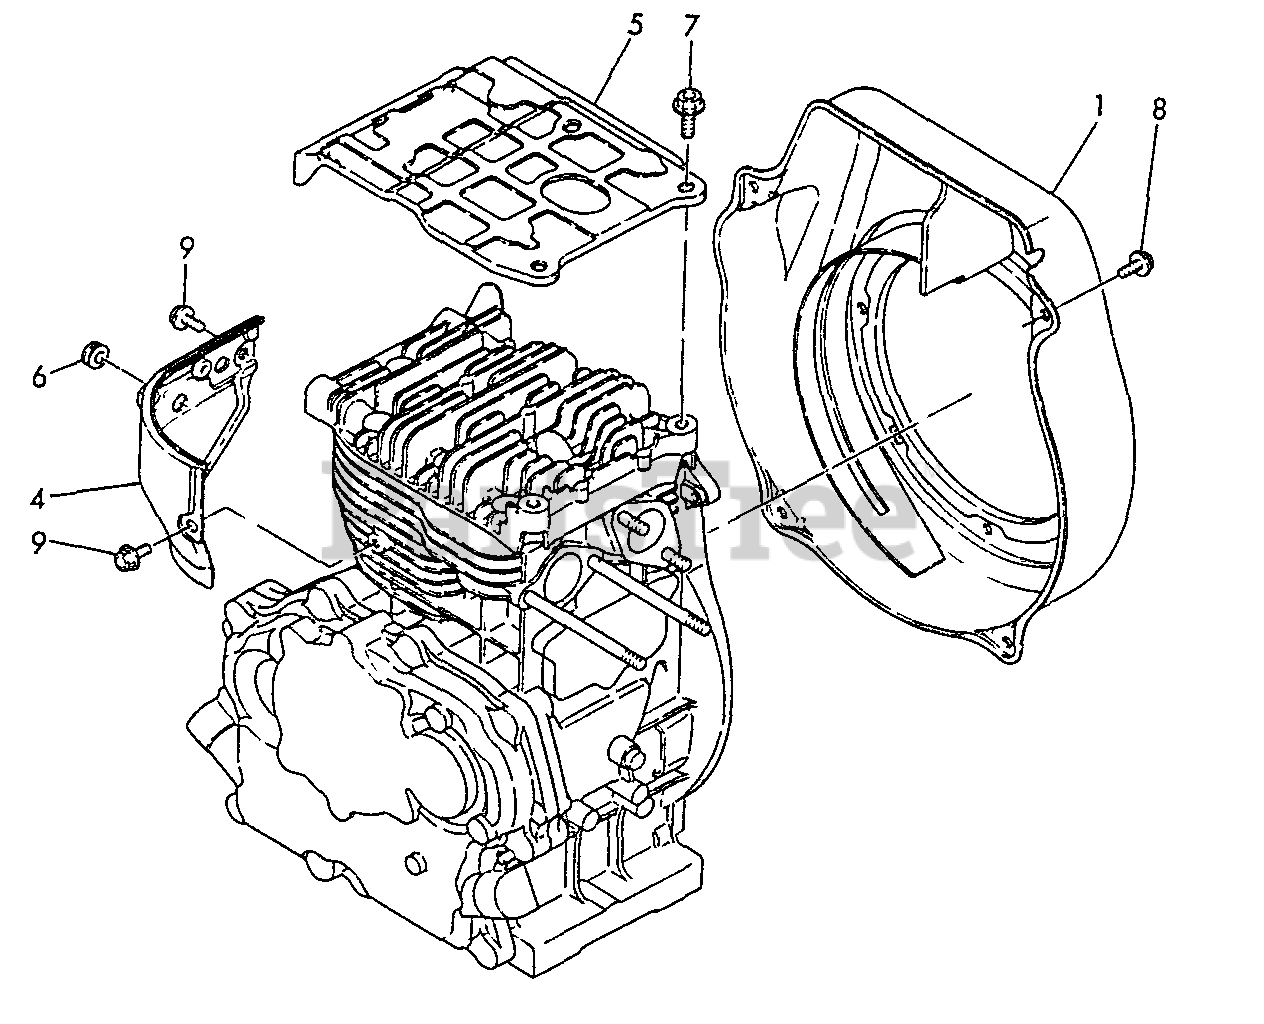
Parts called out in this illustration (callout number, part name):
1	COVER, FAN - INNER
4	SHIELD, CYLINDER
5	COVER, HEAD
6	GROMMET
7	BOLT - 8X20 -- PLATED
8	BOLT - 6X8 -- PLATED
9	BOLT - 6X8 -- PLATED
